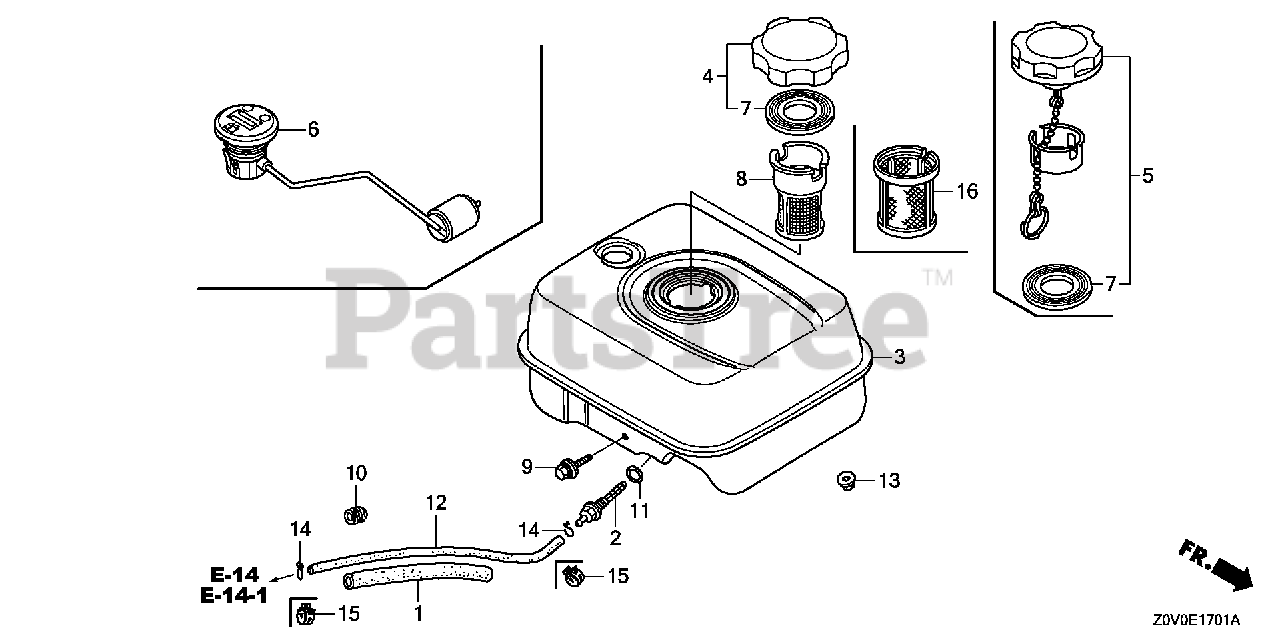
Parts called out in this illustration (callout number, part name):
1	RUBBER, SUPPORTER (107MM)
2	JOINT, FUEL TANK
3	TANK, FUEL *NH31* (MCKINLEY WHITE)
3	TANK, FUEL *NH1* (BLACK)
5	CAP, FUEL FILLER
7	GASKET, FUEL FILLER CAP
7	GASKET, FUEL FILLER CAP (39X62X3) (TOUYOUSYA)
9	BOLT, FLANGE (6X34)
11	O-RING (14MM) (ARAI) Use up to Engine SN 2949254.
11	O-RING (14MM) (NOK)
13	NUT, FLANGE (6MM)
15	CLIP, TUBE (D8)
